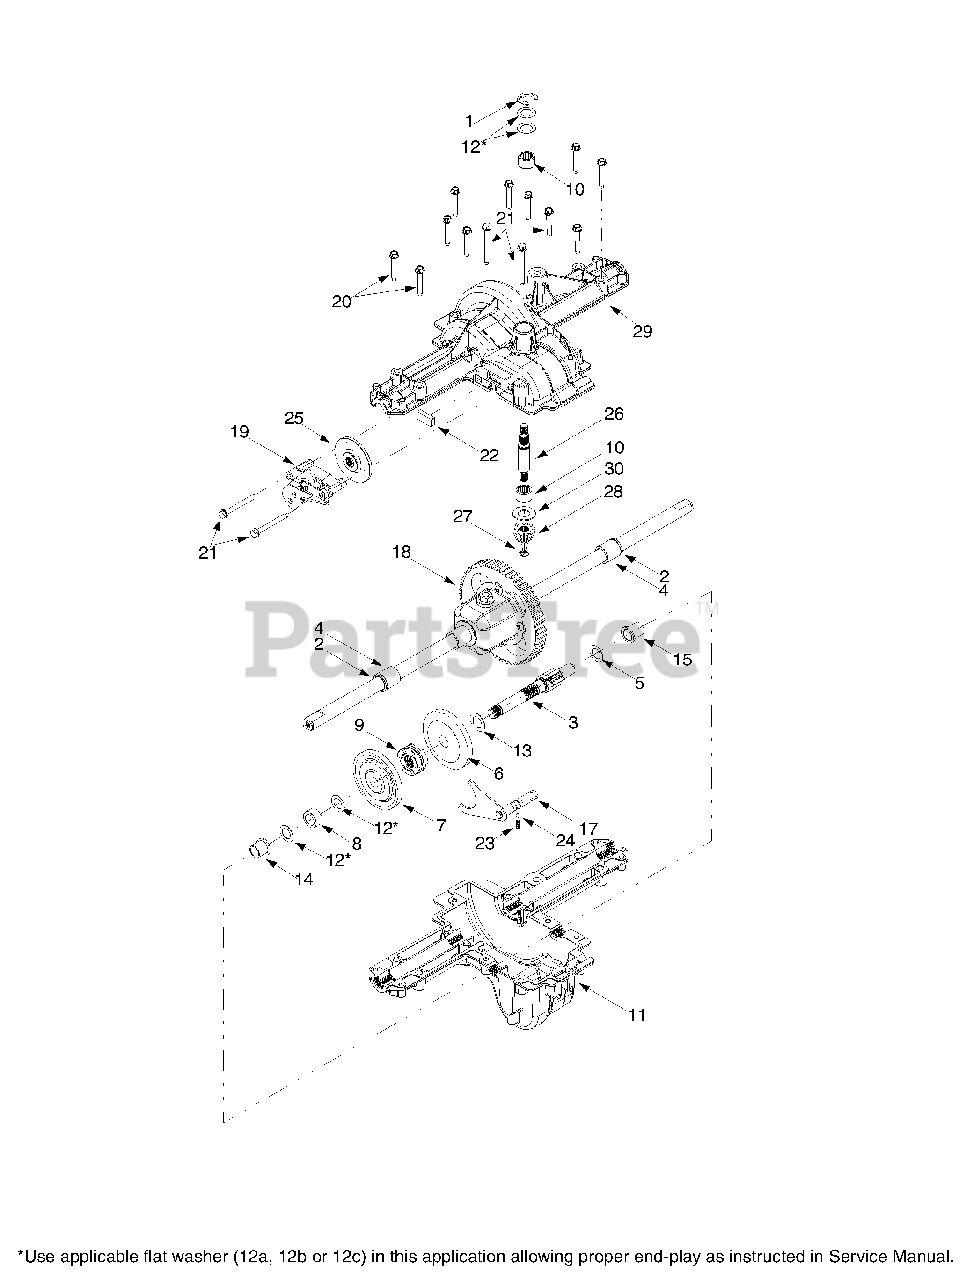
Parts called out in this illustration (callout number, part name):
1	E-Ring, .75
2	Seal, .75 x 1.0 x .125
3	Drive Shaft
4	Sleeve Bearing, .75 x .1.0 x 1.0
5	Thrust Washer, 1.0 x .632 x .0
6	42-Tooth Bevel Gear
7	42-Tooth Bevel Gear
8	Spacer, .633 x 1.0 x .513
9	Clutch Collar
10	Needle Bearing, .625 x .875
11	Lower Housing
13	Flat Washer, .70 x 1.125 x .031
14	Flange Bearing, 5/8 x 3/4 x 3/4
15	Flange Bearing, 5/8 x 3/4 x 15/16
17	Detent Shaft Assembly
18	Differential Assembly
19	Brake Assembly
20	Self-tapping Screw, 1/4-20 x 1.625
21	Self-tapping Screw, 1/4-20 x 2.375
22	Brake Pad
23	Compression Spring
24	Detent Ball
25	Brake Disc
26	Input Shaft
27	Retaining Ring, .437
28	14-Tooth Bevel Pinion
29	Upper Housing
30	Thrust Washer, .635 x 1.25 x .042
